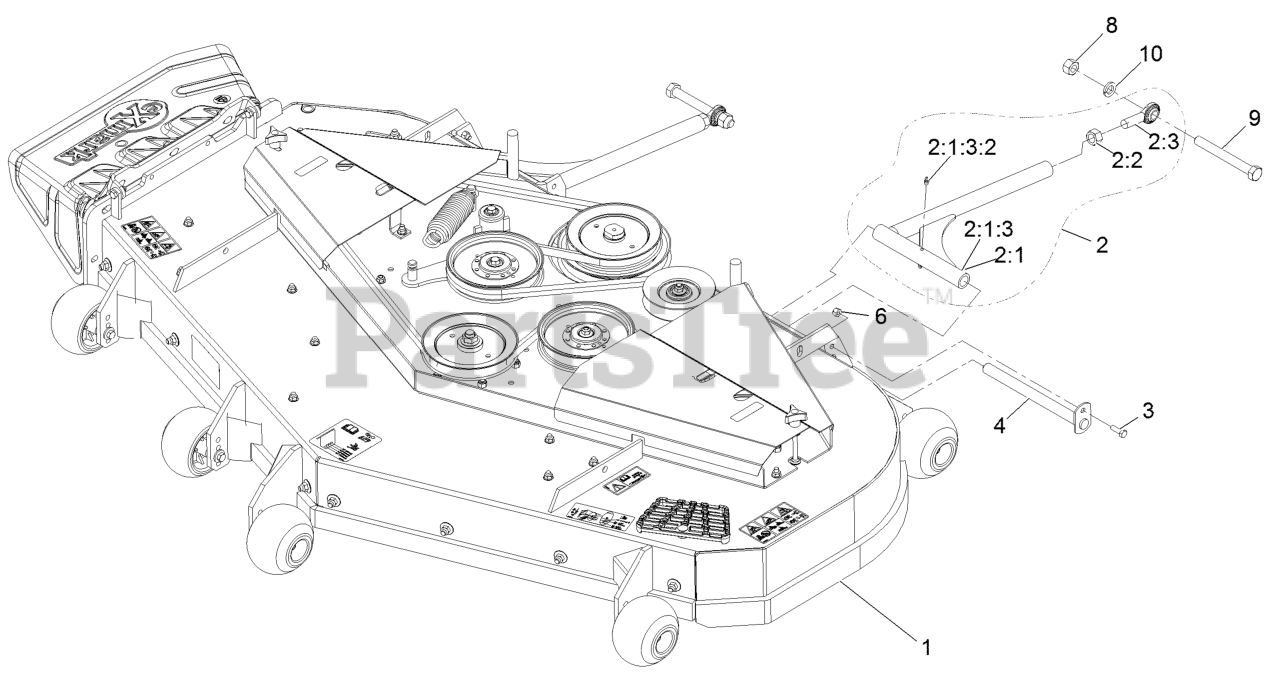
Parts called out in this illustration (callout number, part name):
1	ASM-Deck Complete 725
2	ASM,DECK STRUT XS 72
2:1	WLD,DECK STRUT
2:1:3	Tube And Zerk ASM
2:2	NUT-HEX
2:3	BALLJOINT-SPHERICAL
3	SCREW-HH
4	PIN-STRUT
6	NUT-LOCK, NI
8	NUT-HEX
9	SCREW-HH
10	WASHER-LOCK
